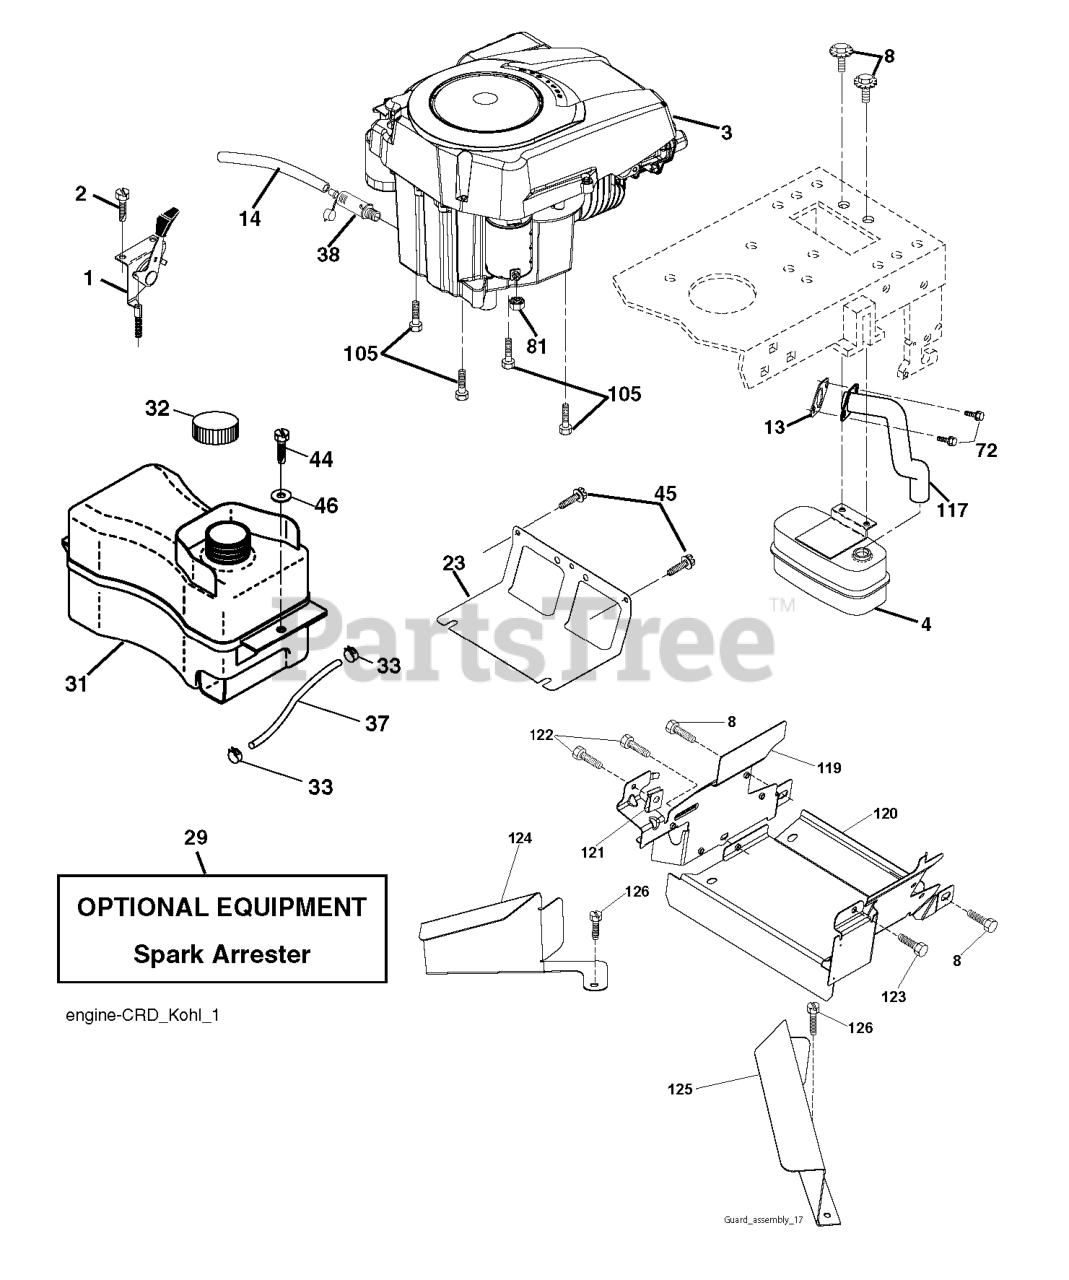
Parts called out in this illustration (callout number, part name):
1	CONTROL.TH/CK.C.
2	SCREW
4	MUFFLER.SINGLE.CYL.KOHL/B&S
8	BOLT.5/16-18UNCX3/4 W/SEMS.BLK
13	GASKET.EXHAUST.KOHLER
14	TUBE, DRAIN OIL ASM.
23	SHIELD.BROWNING.DBR.GUARD
29	KIT.SPARK ARRESTOR 794945 B&S
31	RP TANK FUEL FRT 1.5 GAL
32	FUEL CAP
33	HOSE CLAMP
37	LINE.FUEL.20
38	PLUG DRAIN OIL EASY
44	SCREW HEXWSHR 1/4-20X3/4
45	SCREW, 3/8-16X3/4
72	SCREW.SOCKET HD.5/16-1
81	NUT
105	SCREW 3/8-16X1
117	RP.TUBE.EXHAUST.KOHL.COURAGE
119	LENKRAD
120	GUARD 532199767
122	SCREW.1/4-20X5/8
123	SCREW, 5/16-18 X 1/2
126	SCREW
